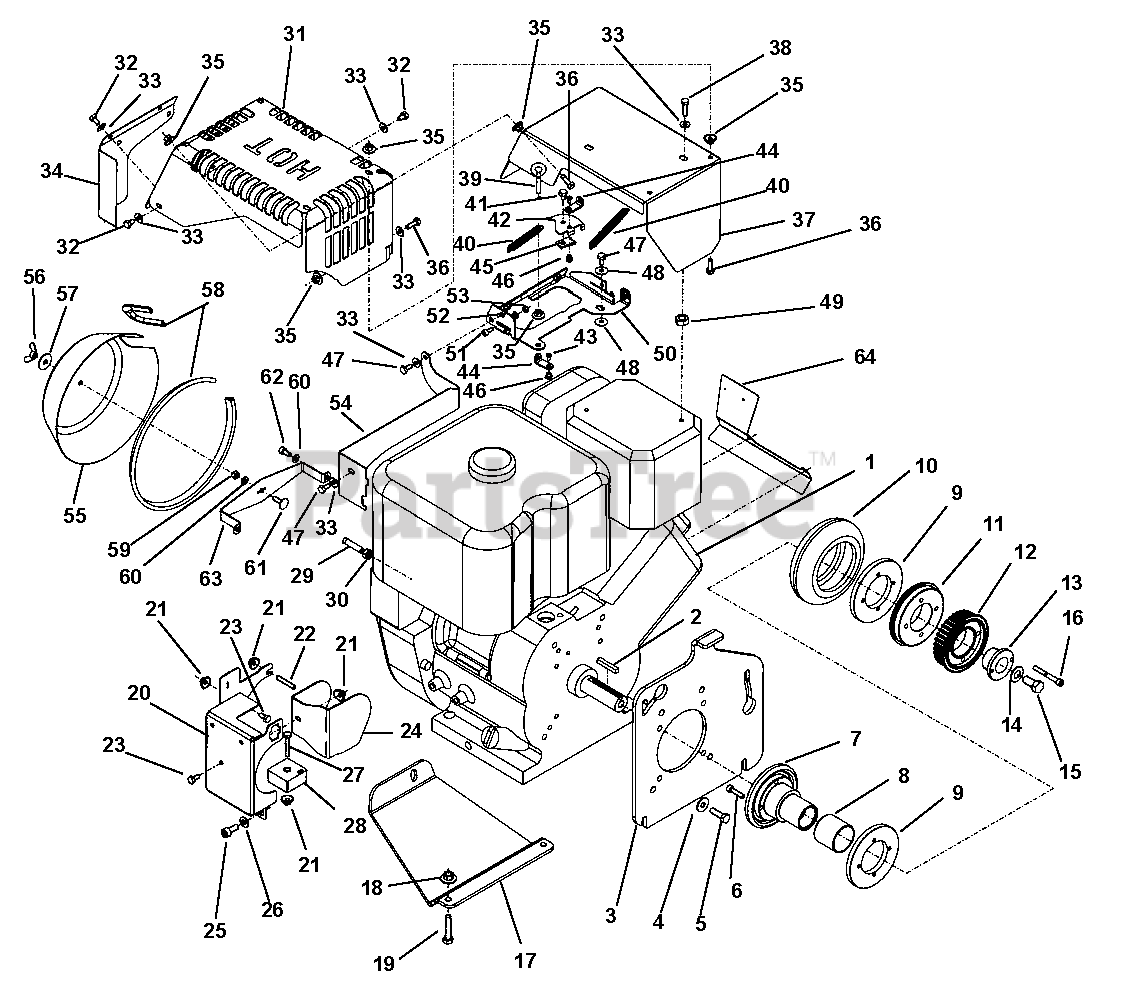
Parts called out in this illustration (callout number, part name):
1	Engine 13 HP Vanguard
3	Plate, Retaining
4	Washer M8
5	Bolt, Hex 5/16 x 1 UNF
6	Bolt, Cylindrical D915 M6 x 25
8	Sleeve, Bearing
9	Jam Piece
11	Jam Piece
13	Connection
15	Bolt, Hex D922 UNF 7/16 x 7/8
16	Bolt, Cylindric D915 M6 x 50
17	Guard, Sheet Metal
18	Nut, Lock M8
19	Bolt, Hex D933 M8 x 40
21	Nut, Flanged M6
22	Stud, Threaded D913 M6 x 35
23	Bolt, Hex D933 M6 x 12
25	Screw D912 M8 x 18
26	Washer, M8
27	Bolt, Hex
28	Regulator, AC
29	Bolt, Threaded M8
30	Nut, Lock D985 M8
31	Shield, Heat
32	Bolt, Hex D933 M6 x 10
33	Washer M6
34	Sheetmetal, Winter
35	Nut, Flanged M6
36	Bolt, Hex D9ss M6 x 18
37	Shield, Heat
38	Bolt, Hex D933 M6 x 22
39	Screw, Ring M6
40	Spring, Tension
41	Screw, Sheet Metal M6.3 x 13
43	Screw, Oval Head M4 x 8
45	Nut, Speed
47	Bolt, Hex D933 M6 x 12
48	Washer M6
49	Nut, Lock D934 M10
51	Screw D912 M5 x 12
52	Washer M5
53	Nut, Hex D934 M5
54	Sheetmetal, Winter
56	Nut, Wing M6
57	Washer 7 x 25 x 1.8
58	878160 Edge Protection N802 6.5 x 8
59	Nut, Hex D934 M6
60	Washer M6
61	Screw M6 x 20
62	Screw D912 M6 x 12
64	Sheetmetal, Winter
